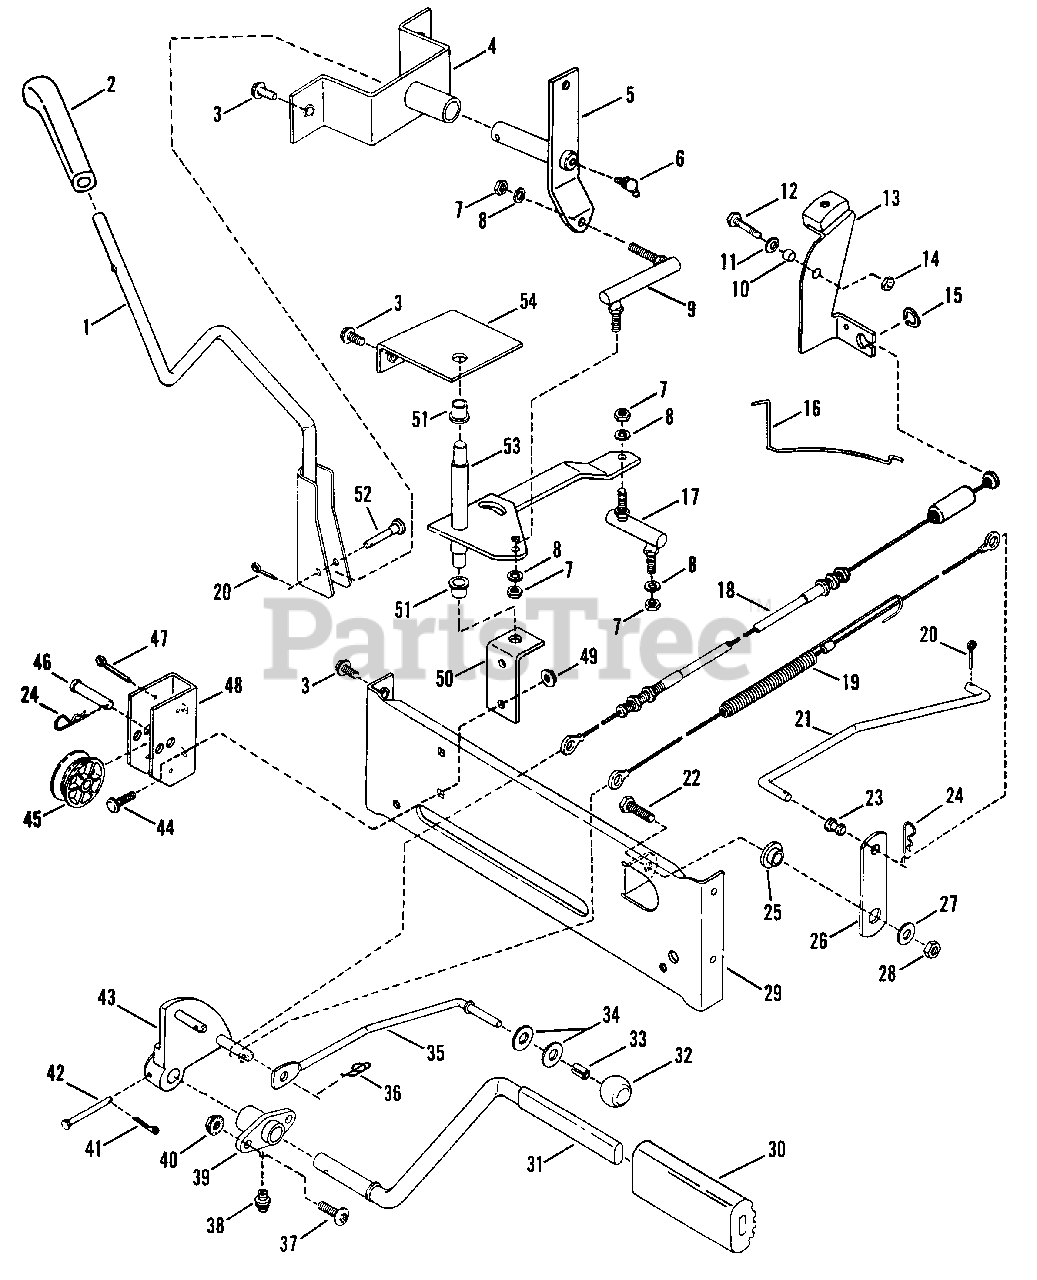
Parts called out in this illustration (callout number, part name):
1	SHIFTER, Transmission
2	KNOB, Shifter
3	SCREW, 5/16-18 x 1/2" Self-Tapping
4	PIVOT, Shifter
5	ARM, Shifter Assembly
6	FITTING, Lube
7	NUT, 5/16-24 Hex
8	WASHER, 5/16 Split Lock
9	LINK, Shift
10	SPACER
11	WASHER, 1/4 SAE Flat
12	SCREW, 1/4-28 x 1" Hex Head Cap
13	LEVER, Brake Assembly
14	NUT, 1/4-28 Hex Lock
15	RING, Retaining
16	SPRING, Brake Return
17	LINK, Shift
18	CABLE, Brake
19	CABLE, Clutch
20	COTTER-PIN, 3/32 x 3/4"
21	ROD, Clutch
22	SCREW, 3/8-24 x 1" Hex Head Cap
23	BEARING, Nyliner
24	PIN, Hair 1.12"
25	SPACER
26	ARM, Pivot
27	WASHER, 3/8 SAE Flat
28	NUT, 3/8-24 Hex Lock
29	BRACE
30	PAD, Pedal
31	PEDAL, Clutch/Brake
32	KNOB, Latch 5/16"
33	RING, Tolerance 5/16" x 1/2"
34	WASHER, Nylon 5/16"
35	LATCH, Clutch/Brake
36	COTTER-PIN, 3/8 Self-Lock
37	SCREW, 5/16-18 x 7/8" Torx
38	FITTING, Lube 3/16"
39	PIVOT, Clutch/Brake Pedal
40	NUT, 5/16-18 Hex Lock
41	COTTER-PIN, 1/16 x 3/4"
42	PIN, 3/16 x 1 1/2"
43	BRACKET, Pedal Pivot
44	BOLT, 1/4-20 x 3/4" Short Neck Carriage
45	SPOOL, Bracket
46	PIN, Clevis, 3/8 x 1 9/32"
47	COTTER-PIN, 1/8 x 1 1/4"
48	BRACKET, Spool (No longer available)
49	NUT, 1/4-20 Hex Flange Lock
50	BRACKET, Pivot
51	BEARING
52	PIN, Clevis, 1/4 x 5/8"
53	LEVER, Shift
54	BRACKET, Shift
